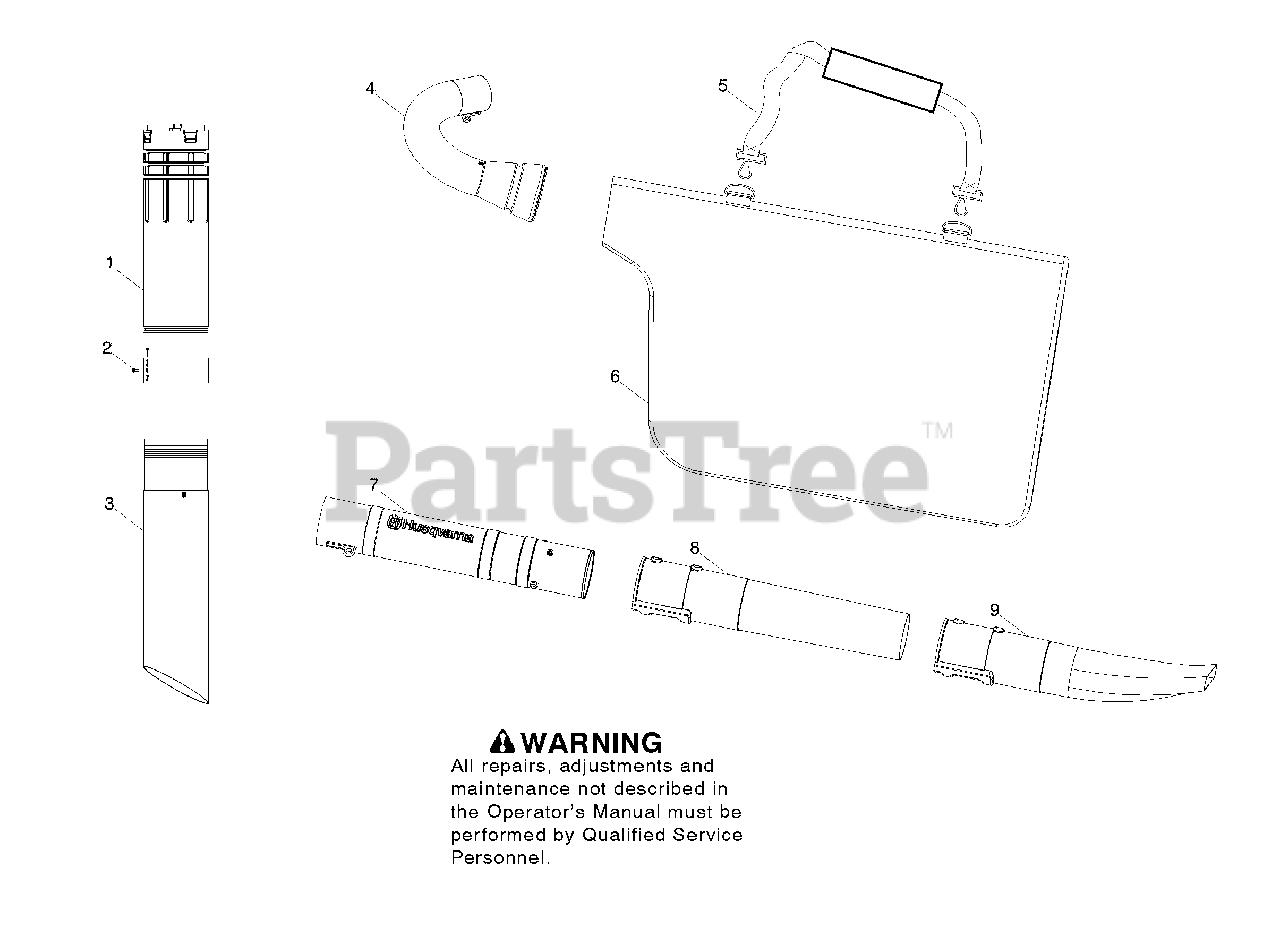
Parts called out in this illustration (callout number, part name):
1	Assy - Upper vac tube with adapter
3	Tube - Lower vac
4	Elbow - Vac
5	Strap - Carrying
6	Assy - Vac bag
7	Assy - Tube - upper blower w/barrier
8	Tube - Lower blower
9	Tube - Lower blower
